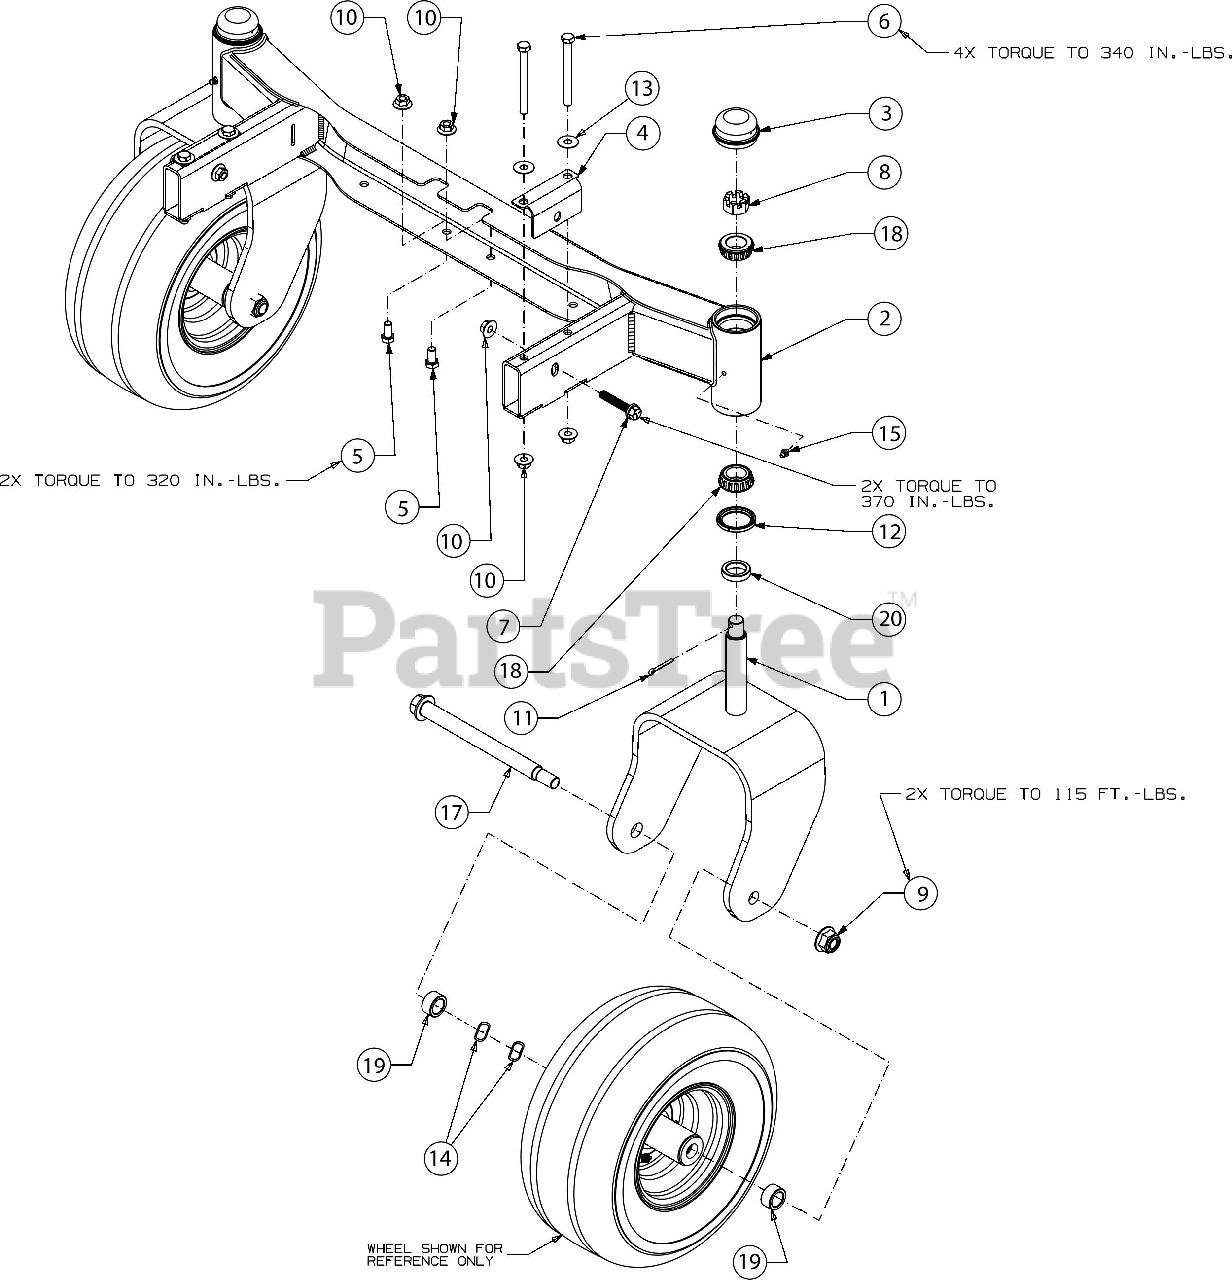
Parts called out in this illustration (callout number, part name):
3	AXLE GREASE CAP
5	HEX SCREW 3/8-16 x .75
6	SCREW 3/8-16 x 3.75 GR5
7	SCREW 3/8-16 x 2.00 GR5
8	HEX NUT CASTLE 3/4-16
9	FLANGE LOCK NUT
10	FLANGE LOCK NUT
11	COTTER PIN-5/32 DIA
13	FLAT WASHER
14	WAVE WASHER .785X1.00X.012
15	GREASE ZERT 1/4-28
17	SHOULDER BOLT
18	ROLLER BEARING 47MM x 25MM x 15MM
